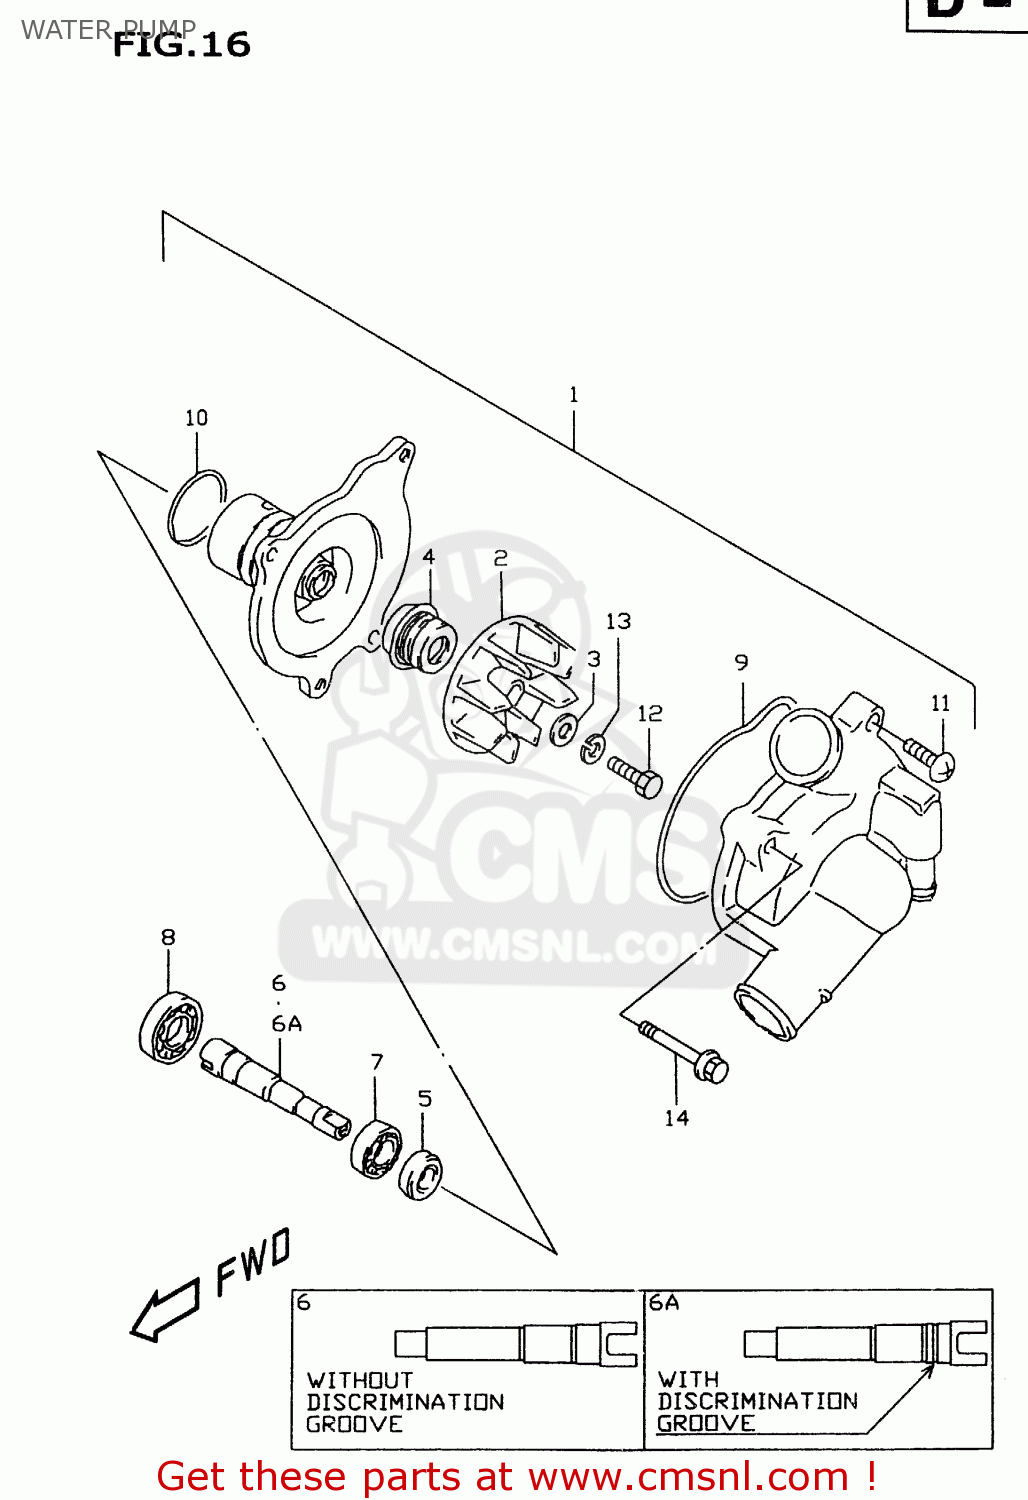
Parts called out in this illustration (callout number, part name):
1	PUMP ASSY,WATER
2	IMPELLER
3	GASKET(6X15X2.2) (NAS)
4	SEAL,MECHANICAL
5	SEAL,OIL(10X21X5)
6	SHAFT,WATER PUMP
6A	SHAFT,WATER PUMP
7	BEARING(10X26X8)
8	BEARING(12X28X8)
9	O RING
10	O RING,WATER PUMP HOLDER
11	SCREW 6X16
12	BOLT(6X13)
13	WASHER
14	BOLT
